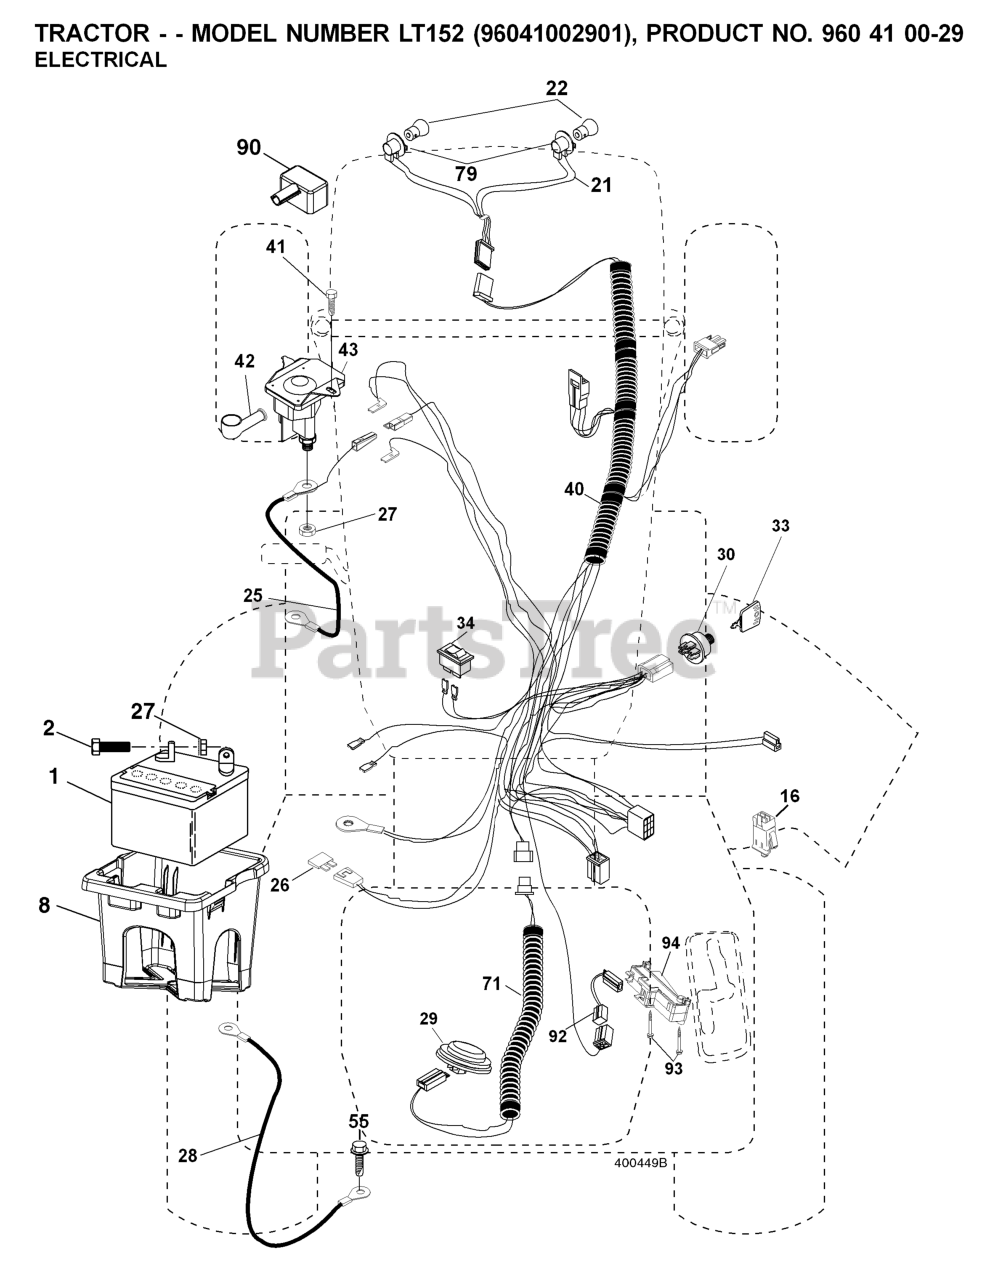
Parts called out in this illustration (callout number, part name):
1	BATTERY 12V .35 AMP
2	BOLT.HEX.1/4.X.3/4.DICHROMATE
8	BOX.BATTERY.MNT.REAR.L
16	SWITCH INTERLOOK PUSH-IN
21	HARNESS.LIGHT W/4152J BULBS
25	CABLE.STARTER.6GA.RED.
26	FUSE 20AMP
27	NUT
28	CABLE.BLACK.18"REAR.BA
29	SWITCH.SEAT.DP W/RAMPS
30	SWITCH.IGN.DELTA.W.LGH.ROS
33	KEY MLD GEN DELTA
40	HARNESS IGN. DASH
41	SCREW
42	TERMINAL COVER
43	SOLENOID.W/BRASS.PLUNGER
55	SCREW 5/16"
71	HARNESS.IGN.CHASS.TEX.REAR.BAT
79	BULB HOLDER ASM.
90	COVER, TERMINAL BATTERY
92	HARNESS.PIGTAIL.CONSLE
93	SCREW.PLASTITE
94	MODULE.REVERSE.ROS
